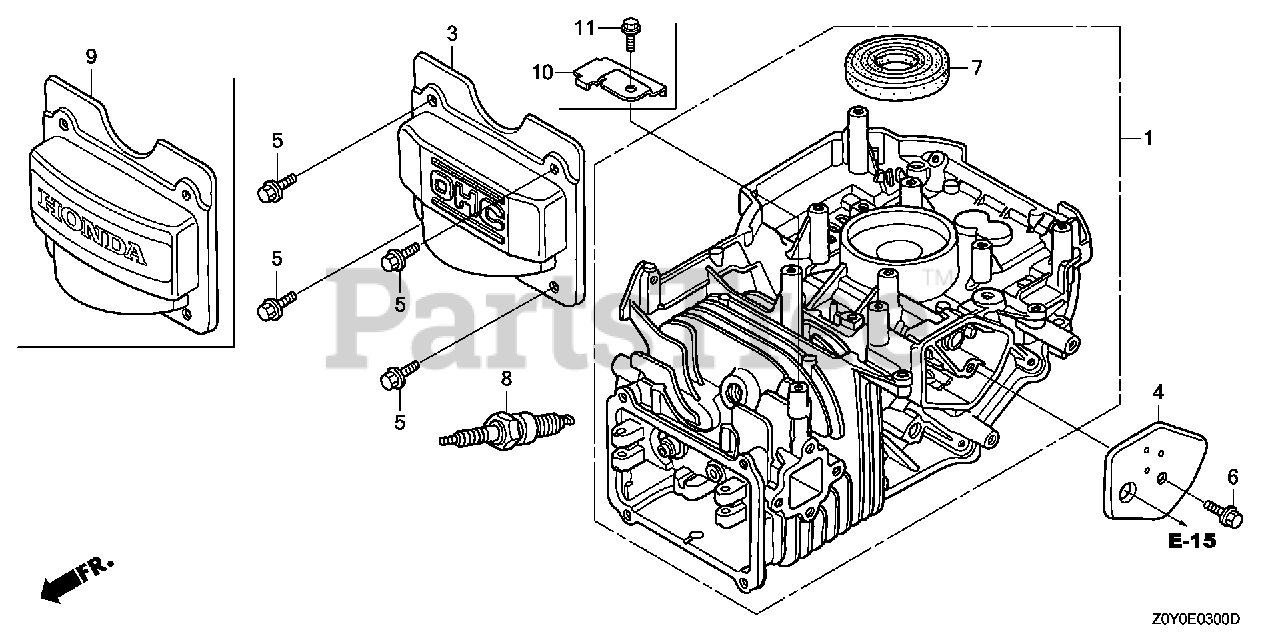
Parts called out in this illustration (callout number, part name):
1	CYLINDER ASSY.
3	COVER, CYLINDER HEAD
4	COVER, BREATHER (BREATHER VALVE ASSY.)
5	BOLT, FLANGE (6X12) (CT200)
6	BOLT, FLANGE (6X14) (CT200)
7	OIL SEAL (25.4X62X6)
8	SPARK PLUG (BPR6ES) (NGK)
